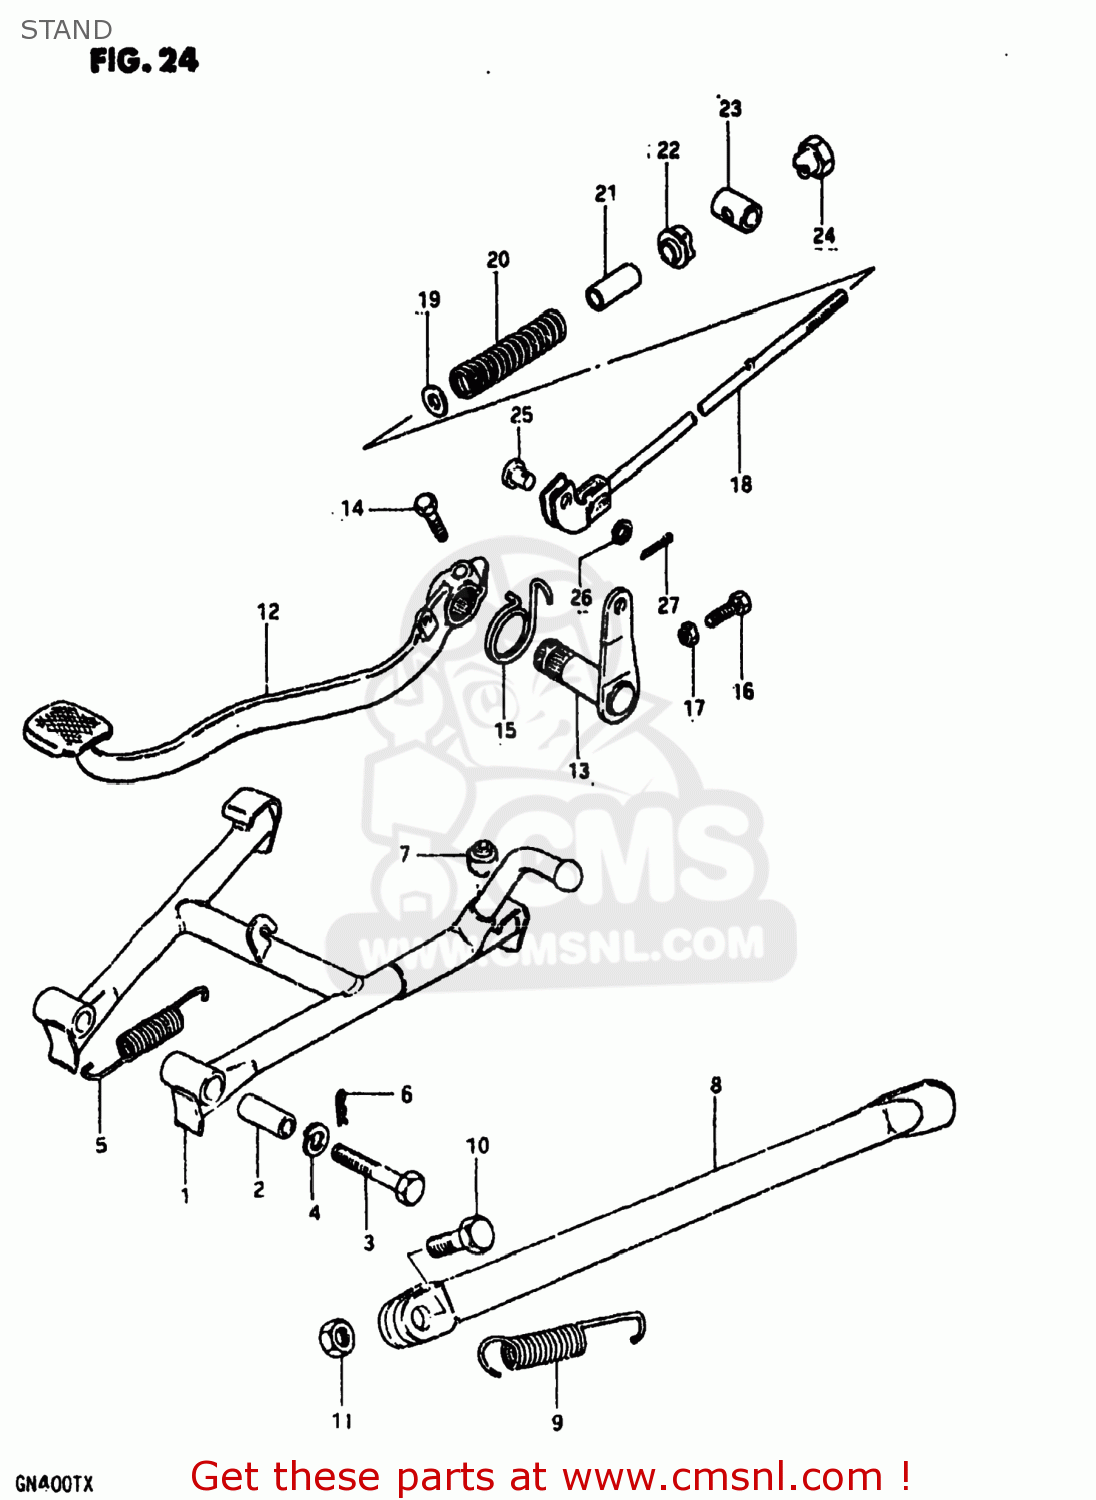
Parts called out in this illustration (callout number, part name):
1	STAND,CENTER
2	SPACER(10X16X38.8)
3	BOLT
4	LOCK WASHER
5	SPRING
6	CLIP
7	CUSHION
8	STAND,SIDE
9	SPRING
10	BOLT(10X30)
11	NUT
12	PEDAL,BRAKE
13	ARM,BRAKE PEDAL
14	BOLT
15	SPRING
16	BOLT(6X23)
17	NUT
18	ROD ASSEMBLY,REAR BRAKE
19	WASHER
20	SPRING
21	CUSHION,FR GRILLE,UPPER
22	CUSHION
23	PIN
24	NUT
25	ROD ASSEMBLY,REAR BRAKE
26	WASHER
27	PIN 20X20
